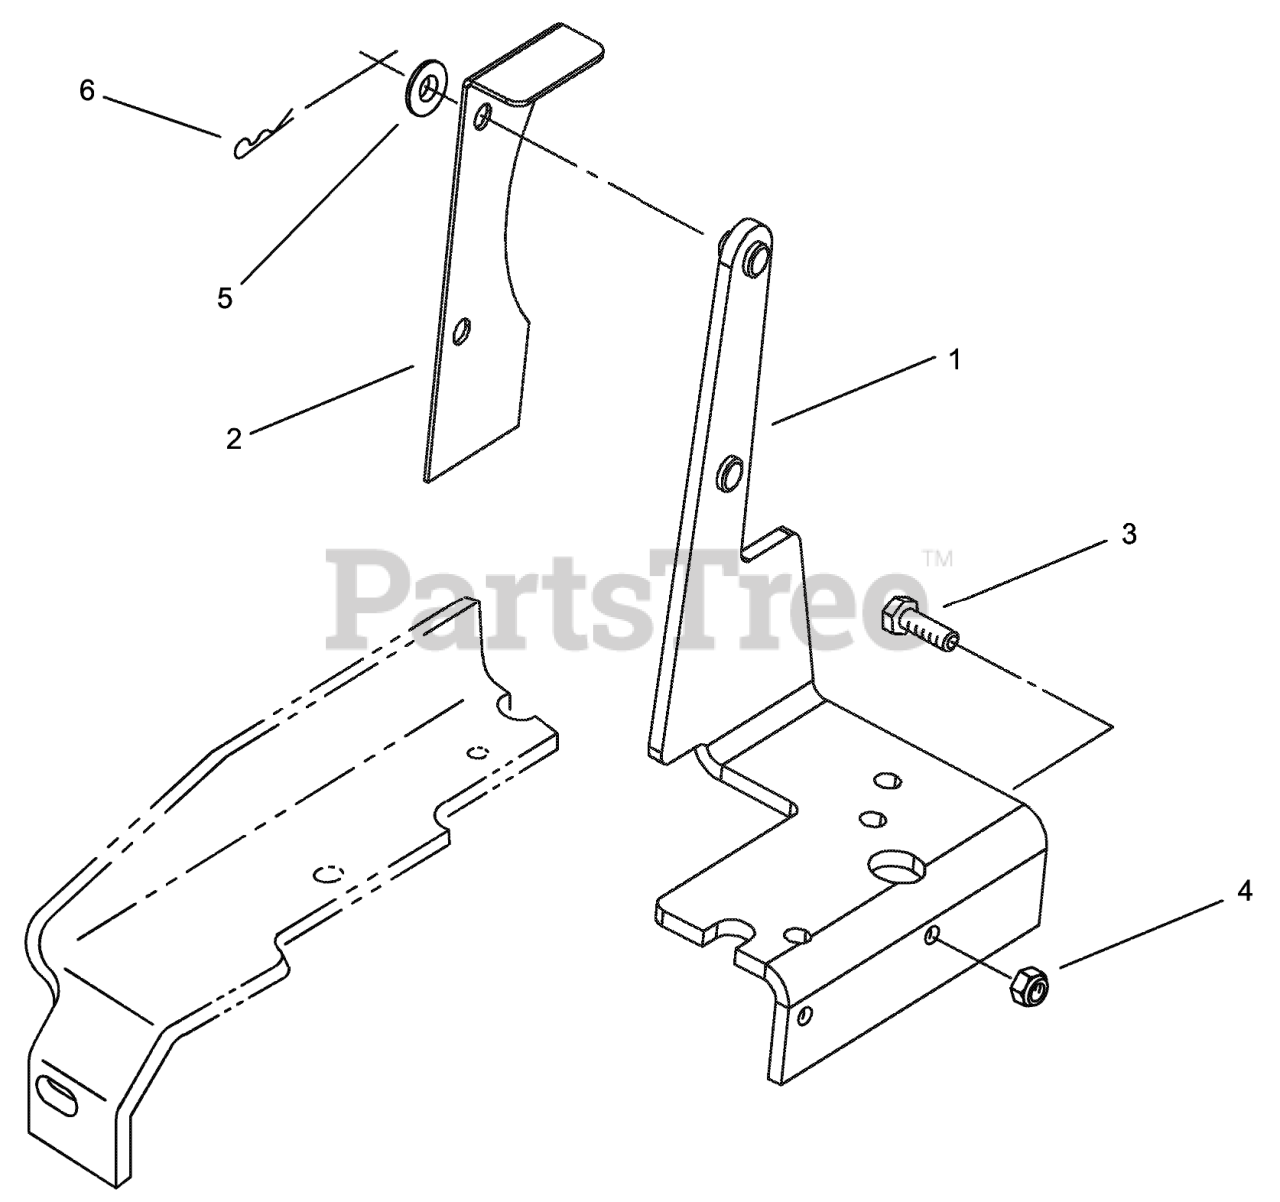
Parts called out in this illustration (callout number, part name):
1	Bracket Guard ASM
2	Guard-Belt
3	SCREW-HH
4	NUT-LOCK, NI
5	WASHER-FLAT
6	PIN-HAIR
